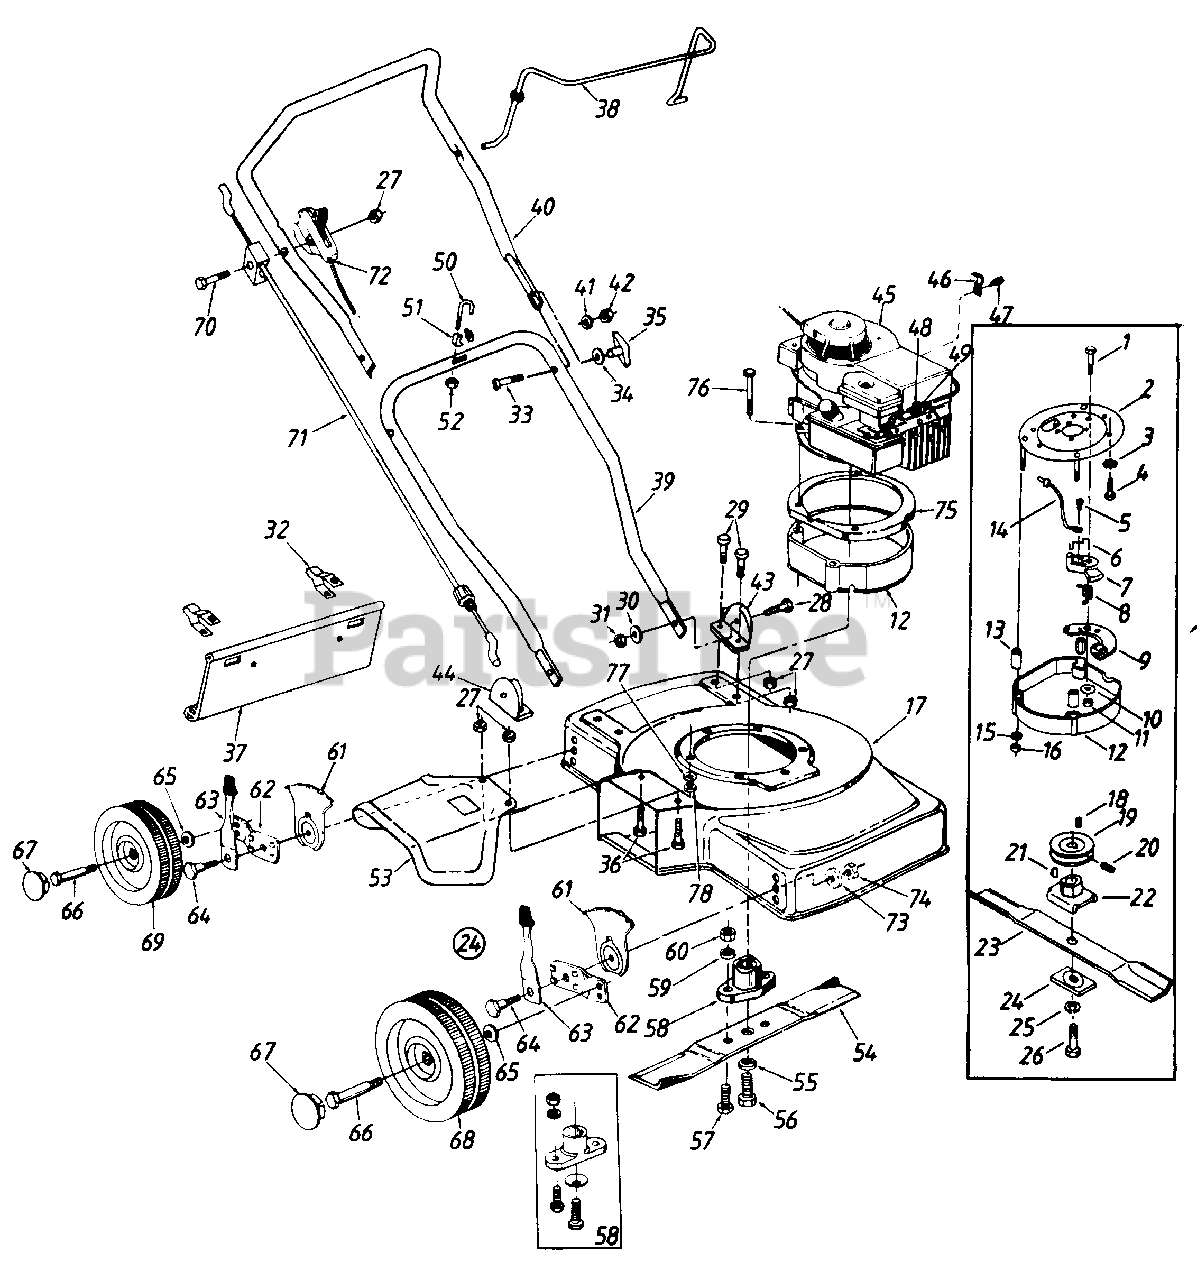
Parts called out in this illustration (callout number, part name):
1	Hex Bolt 3/8-16 x 1.75" Lg.
2	Plate Assembly
3	Int. L-Wash. 1/4" I.D.
4	Hex Bolt 1/4-20 x .62" Lg.
5	Self-Tap Scr. #6-20 x 3/8" Lg.
6	Spring Contact
7	Housing Switch
8	Brake Arm Spring
9	Brake Arm & Pad Ass'y.
10	Fl-Wash. 3/8" I.D. x 1.125" O.D.
11	Hex L-Nut 3/8-16 Thd.
12	Spacer Ring
13	Motor Spacer
14	Wire Harness
15	Fl-Wash. 344n I.D. x .62" O.D.
16	Hex L-Nut 5/16-18 Thd.
17	Deck Ass'y.
18	Square Key 5/32" x 1/2"
19	Pulley-Brake
20	Set Screw 5/16-18 x 3/8" Lg.
21	#6 Woodruff Key 5/32" x 5/8 Dia.
22	Blade Adapter Ass'y.
23	Blade
24	Blade Retainer Piate
25	L-Wash. 3/8" I.D. (H.D.)
26	Hex Bolt 3/8-24 x 1" Lg.
27	Hex L-Nut 1/4-20 Thd.
28	Hex Bolt 3/8-16 x .75" Lg.
29	Hex Bolt 1/4-20 x .5" Lg.
30	Fl-Wash. 3/8" I.D. x .937" O.D.
31	Hex L-Nut 3/8-16 Thd.
32	Hinge Clip
33	Curved Hd. Bolt 5/16-18 x 2" Lg.
34	Curved Washer 5/16" I.D.
35	Knob
36	Carriage Bolt 1/4-20 x 75" Lg.
37	Rear Flap
38	Control Handle
39	Lower Handle
40	Upper Handle
41	L-Wash. 1/4" I.D.
42	Hex Nut 5/16-18 Thd.
43	Handle Bracket-L.H.
44	Handle Bracket-R.H.
45	Engine
46	Cable Clamp
47	Hex B-Tap Scr. #10 x .38" Lg.
48	Cable Clamp
49	Hex AB-Tap Scr. #8 x .38" Lg.
50	J-Bolt
51	Rope Guide Half
52	Hex Sems Nut 1/4-20 Thd.
53	Chute
54	Blade
55	Bell-Wash. .39" I D
56	Hex Bolt 3/8-24 x 1.5" Lg.
57	Hex Bolt 3/8-24 x 1" Lg.
58	Blade Adapter Kit
59	L-Wash. 3/8" I.D.
60	Hex Nut 3/8-24 Thd.
61	Height Adj. Plate
63	Spring Lever Ass'y. w/Knob
64	Shld. Bolt .5" Dia. x .357"
65	Bell-Wash. .40" I.D. x .88"
66	Axle Bolt
67	Hub Cap
68	6" Wheel
69	7" Wheel
70	Hex Bolt 1/4-20 x 2" Lg.
71	Control Cable
72	Throttle Control
73	Bell-Wash. .39" I.D. x 1.38"
74	Hex Nut 3/8-16 Thd.
75	Engine Mounting Cover
76	Hex Bolt 5/16-18 x 2.5" Lg. (Grade 5)
77	L-Wash. 5/16" I.D.
78	Hex Nut 5/16-18 Thd
